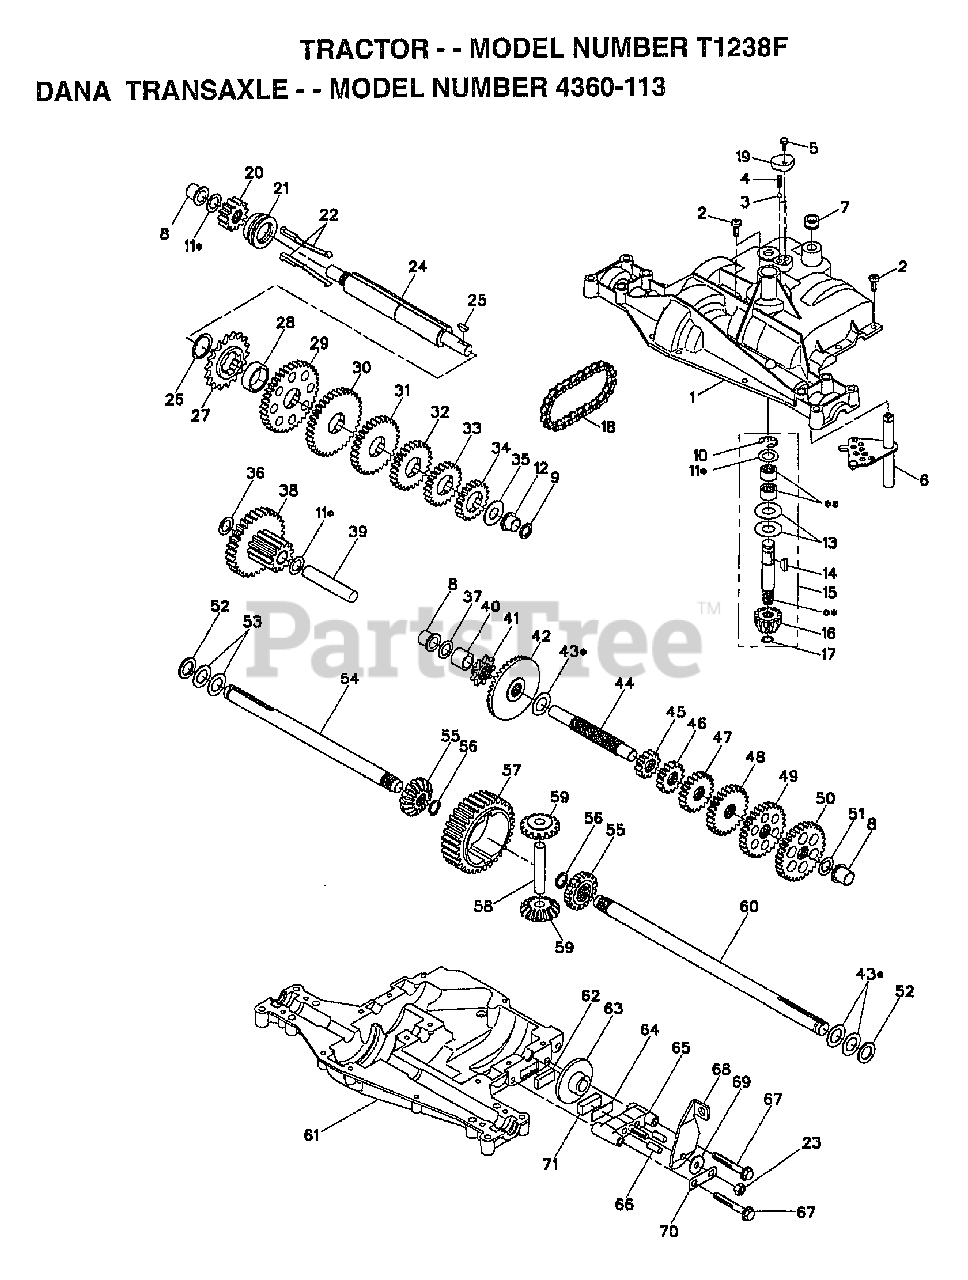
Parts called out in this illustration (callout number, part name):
1	HOUSING.UPPER.DANA.(5305J)
4	"SPRING, DETENT LT"
5	SCREW.TAPPING.1/4-20X.734
6	KIT SHIFTER ASM
9	SEAL.OIL.DAN.5508
10	RETAINING RING LT
11	ASM KIT SHIM 4689
12	BEARING.FLNG.5511
13	WASHER T
14	KEY WOODRUFF-DANA
15	AS KIT INPUT SHFT
16	PINION 14T T
17	"RING,RETAINING LT"
18	"CHAIN,24 PTCH LT"
19	COVER.DETENT.(5584)
20	GEAR.SPUR.12T.(5627)
21	CLUTCH.COL.5467
22	ASM KIT CLTCH KEY
23	NUT.LOCK.5/16-24
24	SHAFT INTERM DANA
25	WOODRUFF KEY
26	"RING,RETAINING LT"
27	SPROCKET 18T T
28	SPACER YT
29	GEAR SPUR 37 TTH
30	GEAR SPUR 35 TTH
31	GEAR SPUR 30T
32	GEAR 25T LT
33	GEAR SPUR 22 TT
34	SPUR GEAR 19T
35	"WASHER, PLAIN LT"
36	WASHER 045
37	WASHER 031
38	ASSY.GEAR.6153 12T&30T
39	SHAFT IDLER
40	SPACER T
41	SPROCKET 9T LT
43	ASM KIT SHIM
44	SHAFT T
45	GEAR SPUR 12 TTH
47	GEAR SPUR 20T
48	"GEAR, SPUR 25T LT"
49	GEAR 28T T
50	"GEAR, SPUR 31T LT"
51	WASHER 060
52	NEOPRENE WASHER
53	WASHER 031
54	AXLE.LH(5528-1)
55	GEAR 15T T
56	RING.RETAINING.(5270)
58	SHAFT T
59	GEAR 1ST T
60	AXLE.RH.(5528-2) DANA
61	HOUSING LOWER TNS
62	PUCK T
63	BRAKE DISC. T
64	SPACER LT
66	PIN T
67	SCREW.(5562) .5/16-18X2.35
69	WASHER LT
70	BRACKET, ANTI-ROTATION
71	PUCK T
